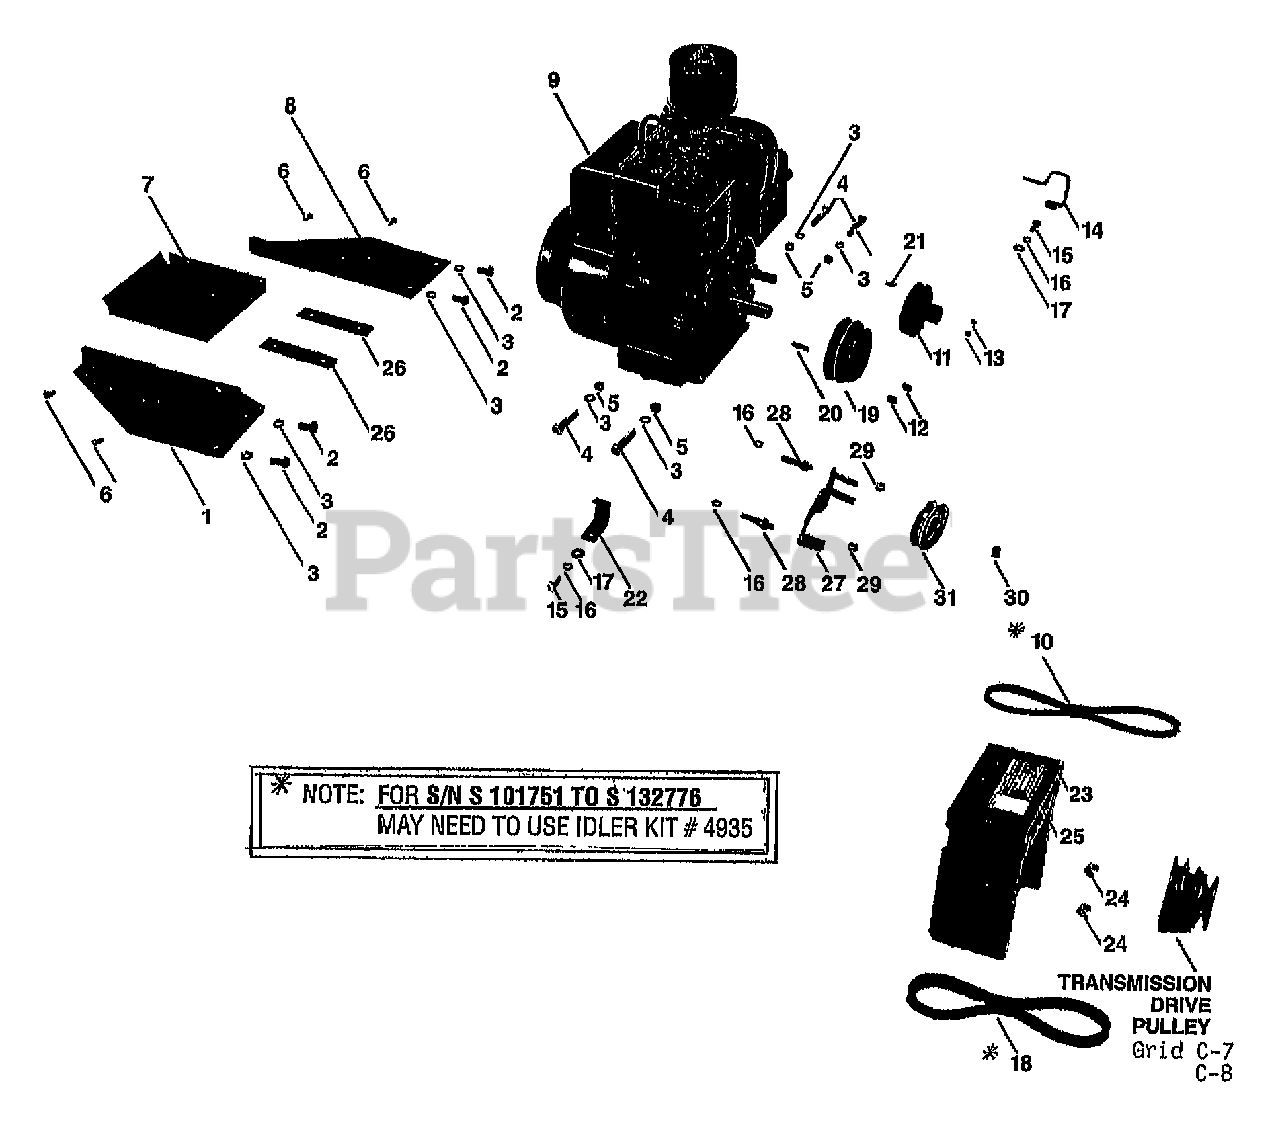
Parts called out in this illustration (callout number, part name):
1	KIT-ENG BRKT LT(OLD 20628)
2	SCR-HHC 5/16-18X.75 GR 5 ZP
3	WASHER-LK .312 ZP
4	SCR-HH 5/16-18X1.75
5	NUT-HEX 5/16-18 ZP
6	SCR-HH SEMS 10-32 X .5 ZP (SEMS - WITH PERMANENT WASHER)
7	PAN-ENG BRKT PNT
8	KIT-ENG BRKT RT(OLD 20627)
9	ENGINE, B&S
10	BELT-V (SEE V-BELT SET BELOW)
11	PULLEY-ENG MACH
12	SCR-SS 5/16-18X.375
13	SCR-SS 1/4-20 X .25
14	GUIDE-BELT FWD
15	SCR-HH 1/4-20X.75 G5 ZP
16	WASHER-LK .25 ZP
17	WASHER-FLAT 1/4 SAE
18	BELT-V GROOVE FWD SMFRAME (SEE V-BELT SET BELOW)
19	KIT-ENG PULLEY PONY
20	KEY-.188 SQX1.0
21	KEY-WOODRUFF #5
22	GUIDE-BELT REV PNT
23	BELT SHROUD W/DECAL (INCL. #25)
24	NUT-WING/LK 5/16-18 ZP
25	DECAL-BELT POSITION
26	SHIM-4.38X.88X.134
27	BRKT-IDLER WELD PNT
28	STUD-5HP (B&S PART)
29	NUT-LK 1/4-20
30	NUT-H/LK 3/8-16
31	IDLER-"V" GROOVE (INTERNAL BUSHINGS TYPE)
